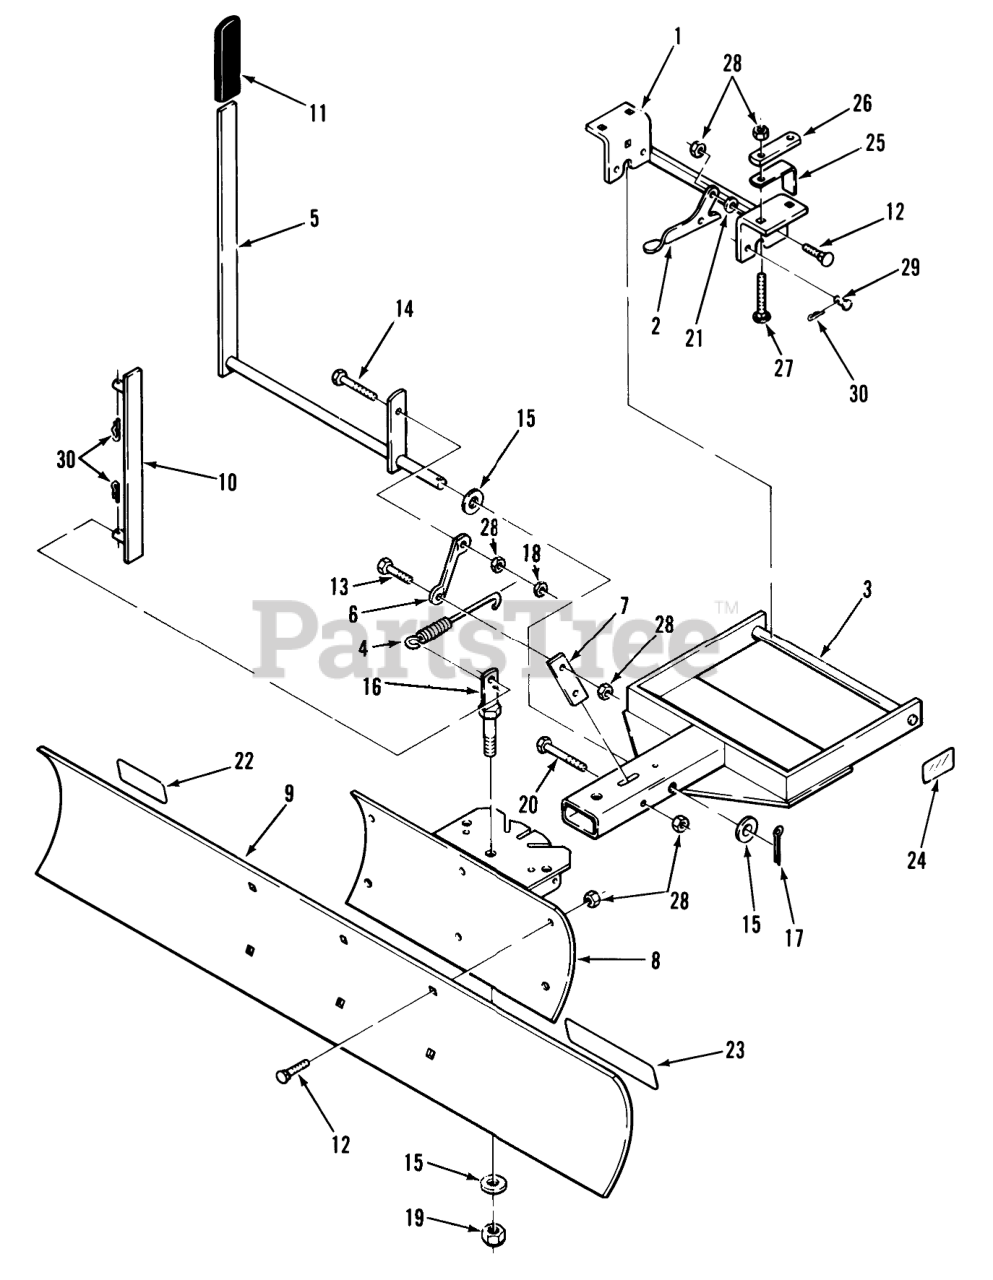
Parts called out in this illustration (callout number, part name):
1	Bracket
2	PLATE-LATCHING
3	ASS'Y-FRAME R
4	SPRING
5	ASS'Y-LATCH HANDL R
6	Latch Link
7	Latch
8	ASS'Y-QUADRANT
9	Blade
10	Lift Link
11	GRIP
12	Bolt
13	BOLT
14	Bolt
15	Washer
16	Wa-Scrw
17	Cotter Pin
18	NUT-HEX, JAM
19	Nut
20	HHCS
21	Washer
22	DECAL-CAUTION
23	DECAL WHEEL HORSE
24	DECAL-OVERLAY
25	SPACER-BRACKET
26	BRACKET-REAR LINK MOUNTING
27	Bolt-Carriage
28	NUT
29	Pin
30	Hairpin
